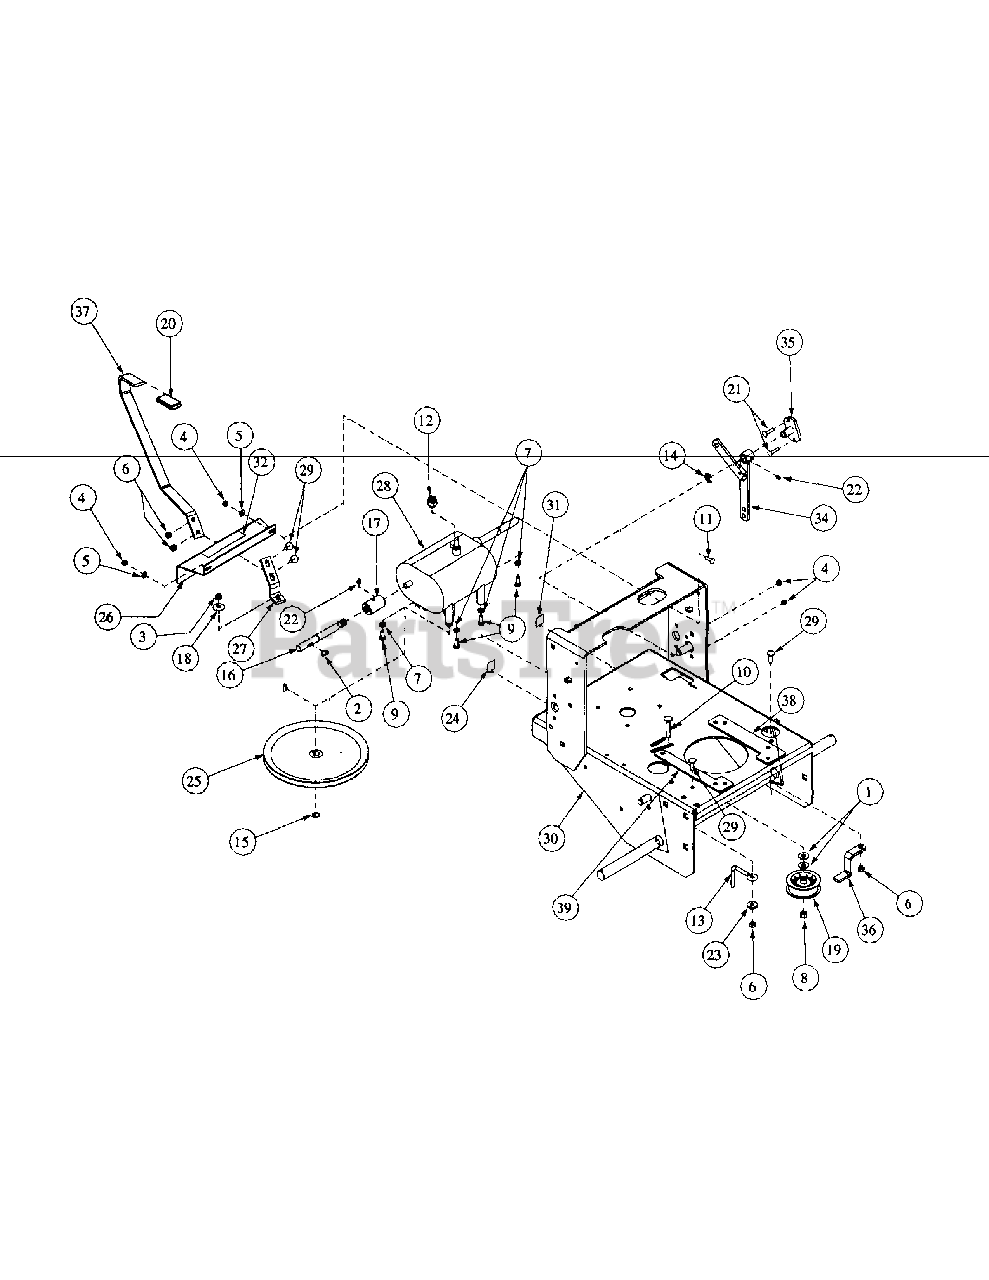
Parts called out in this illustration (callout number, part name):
1	Flat Washer, 3/8 Zinc
2	Woodruff Key, 3/16 x 3/4
3	Jam Nut, Insert Lock, 3/8-24
4	Lock Nut, Nylon Insert, 1/4-20
5	Flat Washer, 1/4 Zinc
6	Nut, 5/16-18 Nylock
7	Lock Washer, 5/16 Zinc
8	Lock Nut, Nylon Insert, 3/8-16
9	Hex Cap Screw, 5/16-18 x 3/4
10	Carriage Bolt, 3/8-16 x2
11	Carriage Bolt, 1/4-20 x .750
12	Switch, WB Transmission
13	Drive Belt Guide
14	E-Ring, 5/8
15	External Retainer Ring
16	Jackshaft w/ Heavy Spline
17	Coupling w/Heavy Spline
18	Bell Washer, .39 ID x 1.13 OD x .062
19	Flat Idler Pulley w/Adapter
20	Grip, .250 x 1 x 3-1/2, Yellow
21	Carriage Bolt, 1/4-20 x 1.00
22	Grease Fitting, 1/4-28 x 3/16
23	Idler Washer
24	Decal "Made In America"
25	Transmission Pulley
26	Shift Plate
27	Shift Arm
28	Transmission, 5 Speed
29	Carriage Bolt, 5/16-18 x 1
30	Engine Deck Assembly
31	Label, Warning, Open Belt Drive
32	Label, Mower Instruction
34	Clutch, Bellecrank Weldment
35	Bellecrank Pivot, Weldment
36	Engine Belt Guide
37	Shift Handle
38	Engine Spacer, RH
39	Engine Spacer, LH
